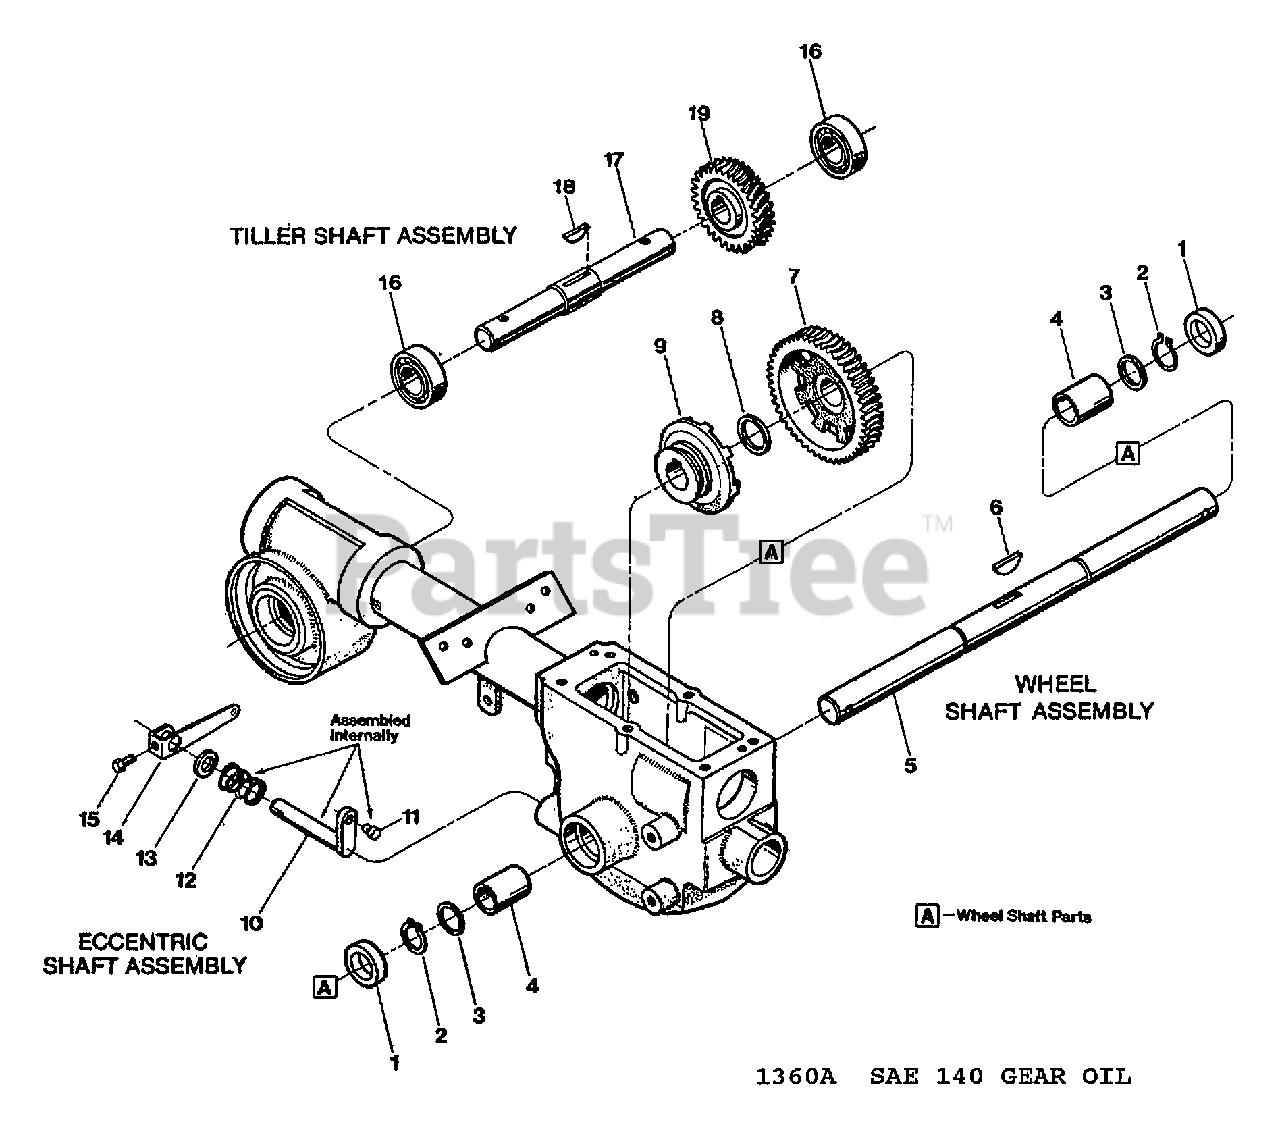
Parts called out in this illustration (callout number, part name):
1	SEAL-OIL WHEELSHAFT
2	RING-HEAVY EXT .906 ID
3	SHIM-1.375X1.015X.062
3	SHIM-1.375X1.015X.03
3	SHIM-1.375X1.015X.015
3	SHIM-1.375X1.015X.01
4	BUSHING-1.25X1.005X1.5
5	ASSM-WHEEL SHAFT (AXLE) W/KEY (INCL. 6)
6	KEY-HI PRO .25X1.312
7	GEAR-WORM 46 TEETH MACH
8	WASHER-1.468X1.016X.062
9	CLUTCH-MACH
10	WELD-ECCENTRIC
11	PIN-.375 X .72
12	SPRING-.850 X .875 LONG
13	SEAL-OIL ECCENTRIC
14	LEVER-CABLE ADJ PNT
15	SCR-HH 1/4-20X.5 GR5 YEL
16	BEARING-BALL
17	SHAFT-W/KEY (TILLER)
18	KEY-WOODRUFF .25X1.12
19	GEAR-TILLER MACH
